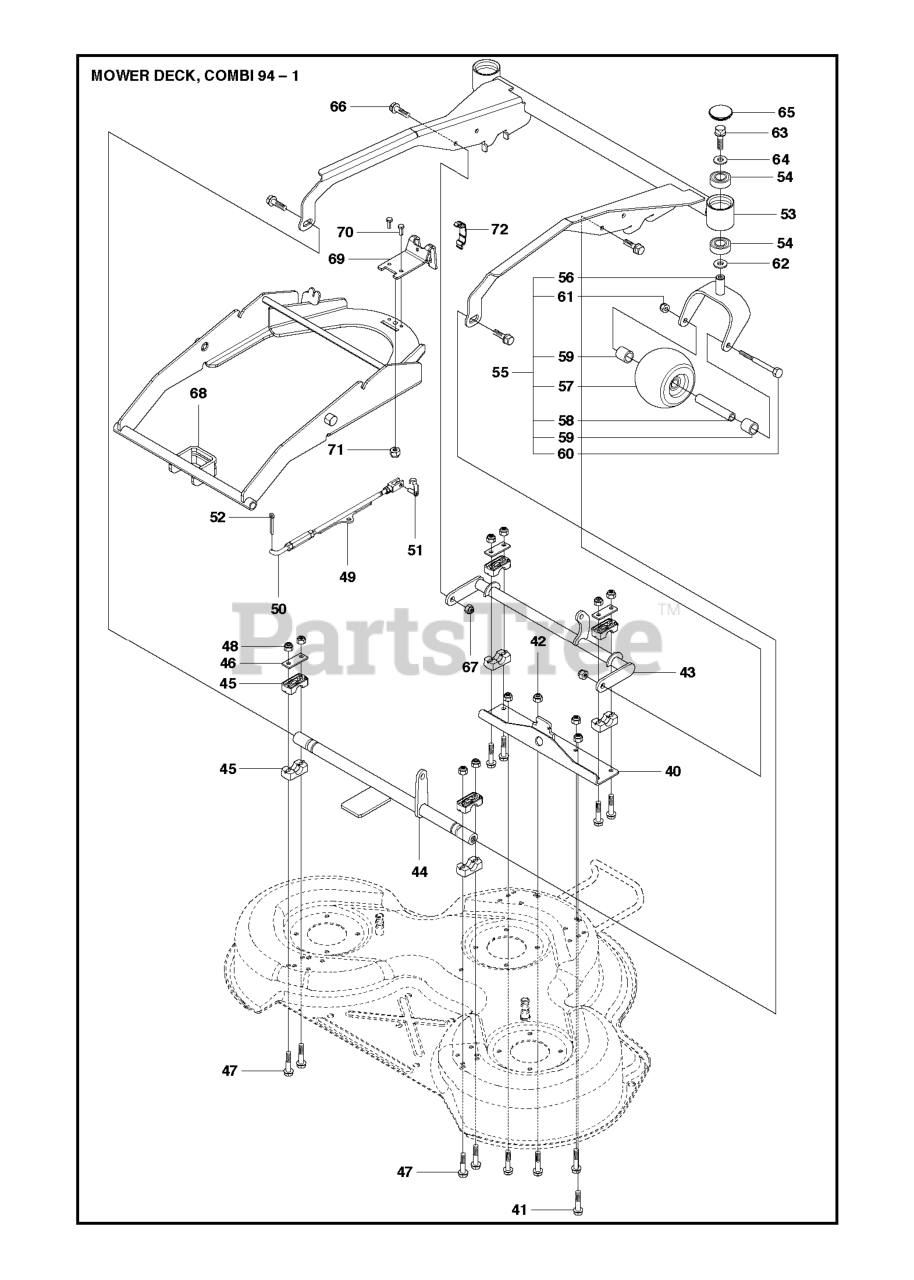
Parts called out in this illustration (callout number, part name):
42	LOCKNUT M8
48	LOCKNUT M8
50	PARALLEL ROD
54	BALL BEARING 6004-2RS1
55	PIVOT WHEELS
57	DECK ROLLER, FRONT
61	NUT
65	HUB CAP PIVOT WHEEL
67	LOCKNUT M8
70	SCREW
71	LOCKNUT M8
72	CLIP GRAY
